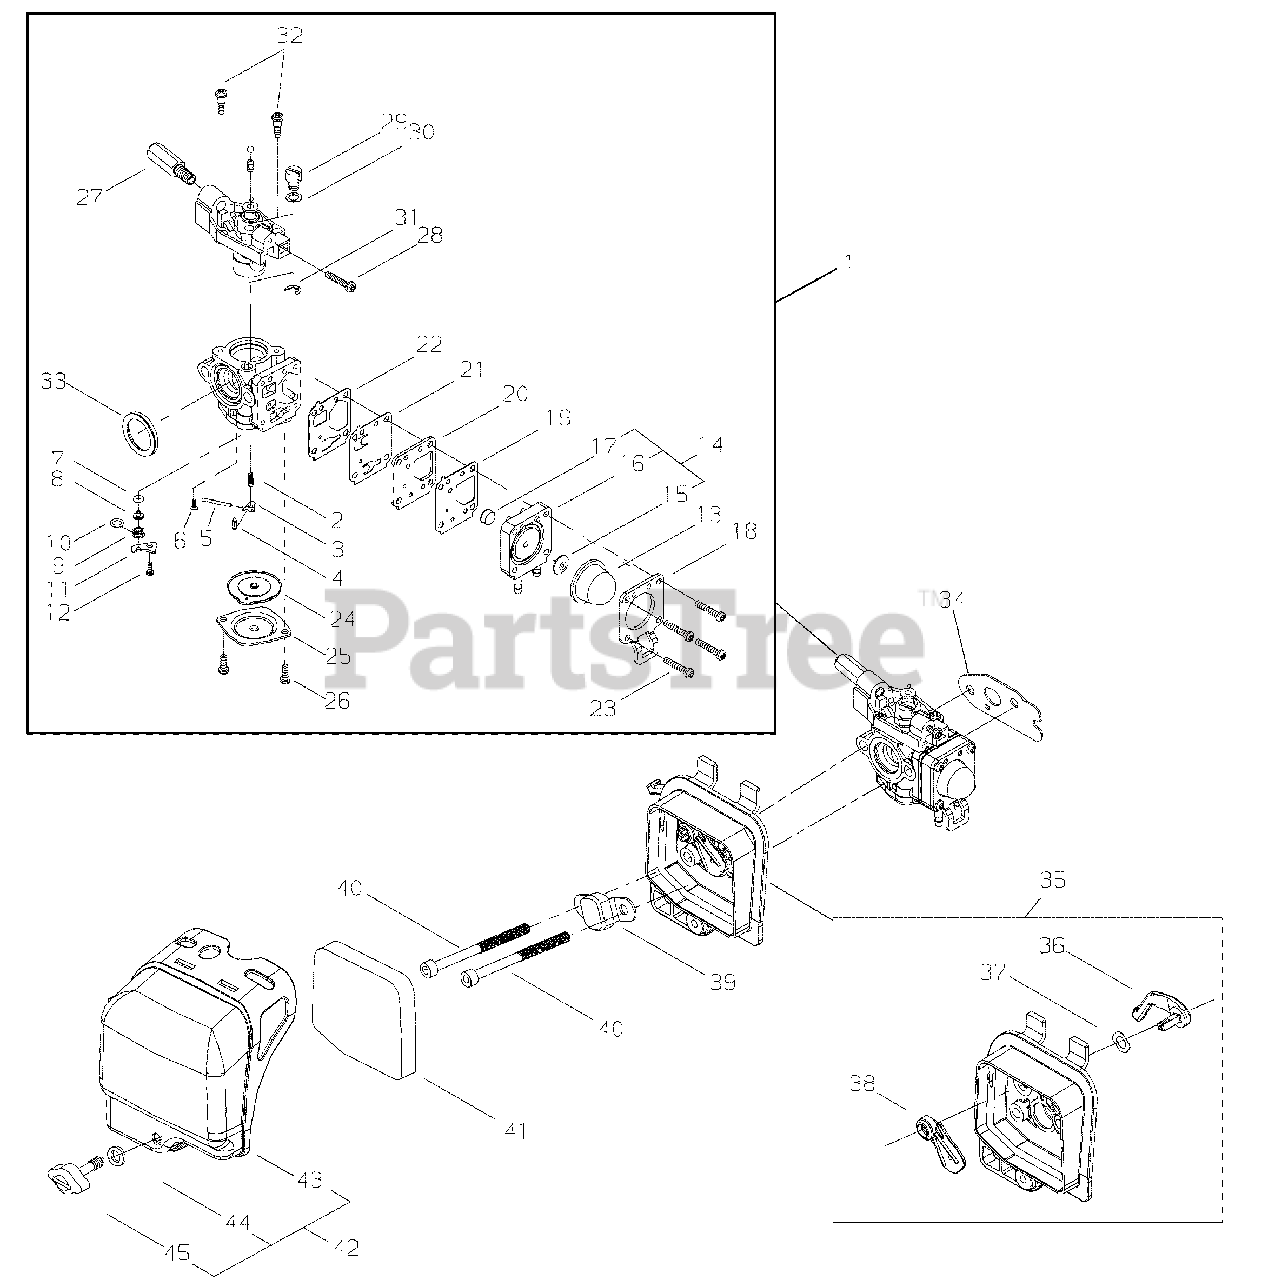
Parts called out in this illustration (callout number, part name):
1	CARBURETOR
2	SPRING, METERING LEVER
3	LEVER, METERING
4	VALVE, INLET NEEDLE
5	PIN, METERING LEVER
6	SCREW, METERING LEVER PIN
8	JET, MAIN
9	VALVE, CHECK
13	BULB, PURGE
14	PUMP COVER ASSY
15	VALVE
16	COVER, PUMP
17	SCREEN, SPARK ARRESTOR
18	PLATE
19	GASKET
20	PLATE, PUMP
21	DIAPHRAGM, PUMP
22	GASKET
23	SCREW
24	DIAPHRAGM, METERING
25	COVER, DIAPHRAGM
27	NUT, CABLE ADJUST
28	SCREW, IDLE ADJUST
31	RING, RETAINING
33	SEAL
34	GASKET, INTAKE
35	AIR FILTER CASE ASSY
36	LEVER, CHOKE
37	WASHER - SPRING
38	PLATE, CHOKE
39	PLATE, PREVENT
40	SCREW - 5X60
41	FILTER, AIR
42	AIR FILTER COVER ASSY
43	COVER, AIR FILTER
44	WASHER - VINYL
45	THUMBSCREW
